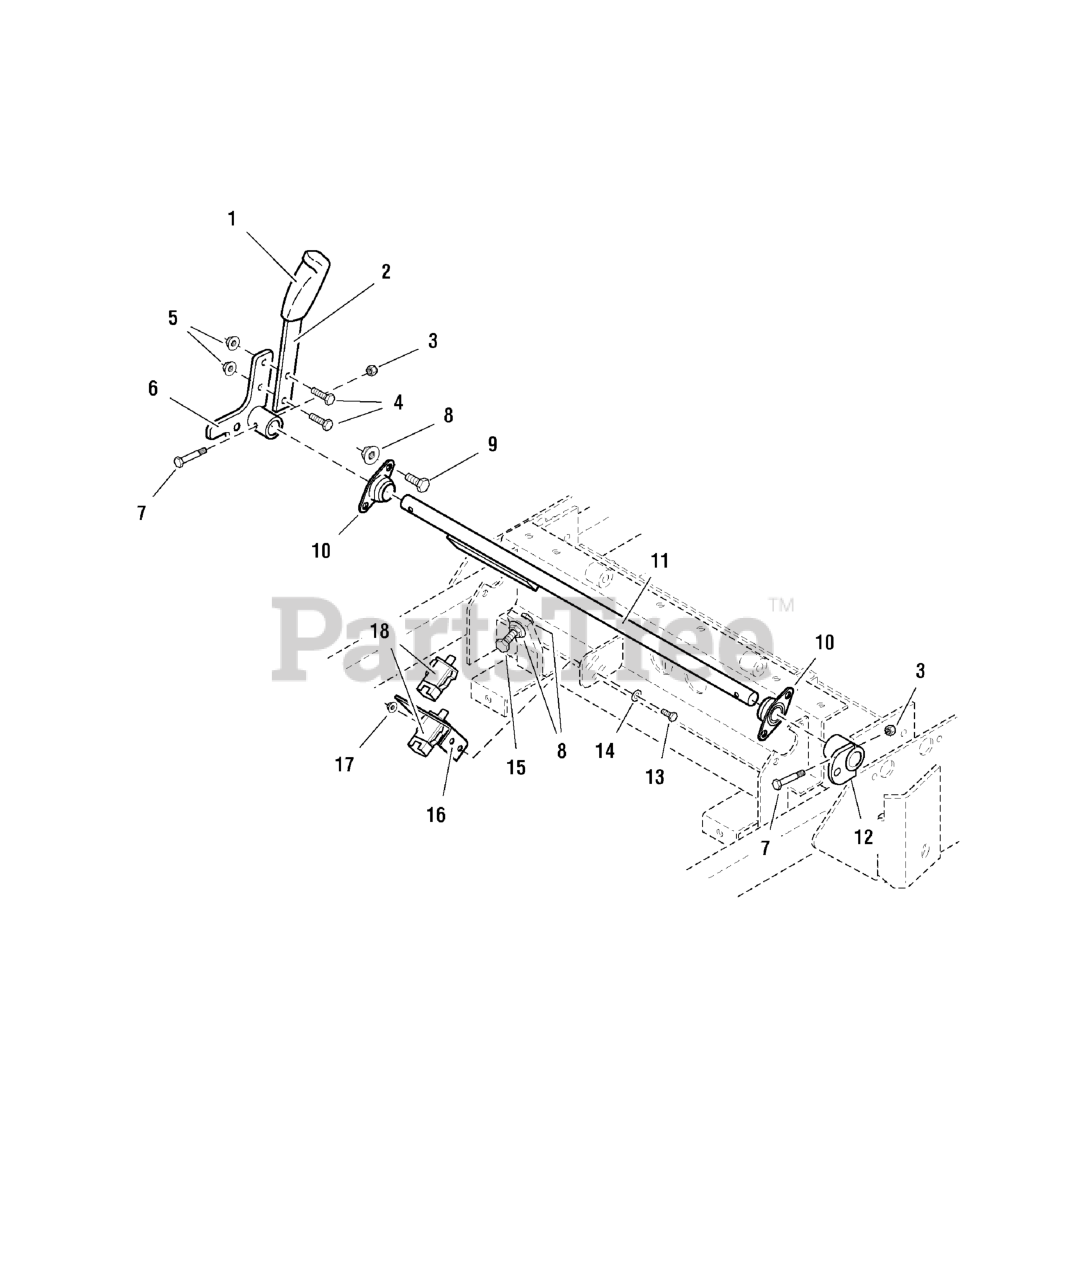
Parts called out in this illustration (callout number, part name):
1	GRIP
2	BRAKE HANDLE
3	NUT, 1/4-20 HEX NYLON LOCK
4	BOLT, 5/16-18 X 1 GD5 YZ
5	NUT, 5/16-18 HEX SERRATED FLANGE (SMALL)
6	BRAKE HANDLE MOUNT
7	BOLT, 1/4-20 x 1-3/4
8	NUT, 3/8-16 Hex Serrated Flange
9	BOLT, 3/8-16 X 3/4" GD5 CZ
10	BEARING, Flange
11	BRAKE HANDLE SHAFT
12	PIVOT, LINKAGE MOUNT WELDMENT - BLK
13	BOLT, 1/4-20 x 3/4
14	WASHER, 1/4 SAE
15	BOLT, 3/8-16 x 1-3/4 TFL
16	SWITCH MOUNT BRACKET
17	NUT, 1/4-20 HEX SERR. FLANGE
18	SWITCH, DP NO/NC SNAP-IN
